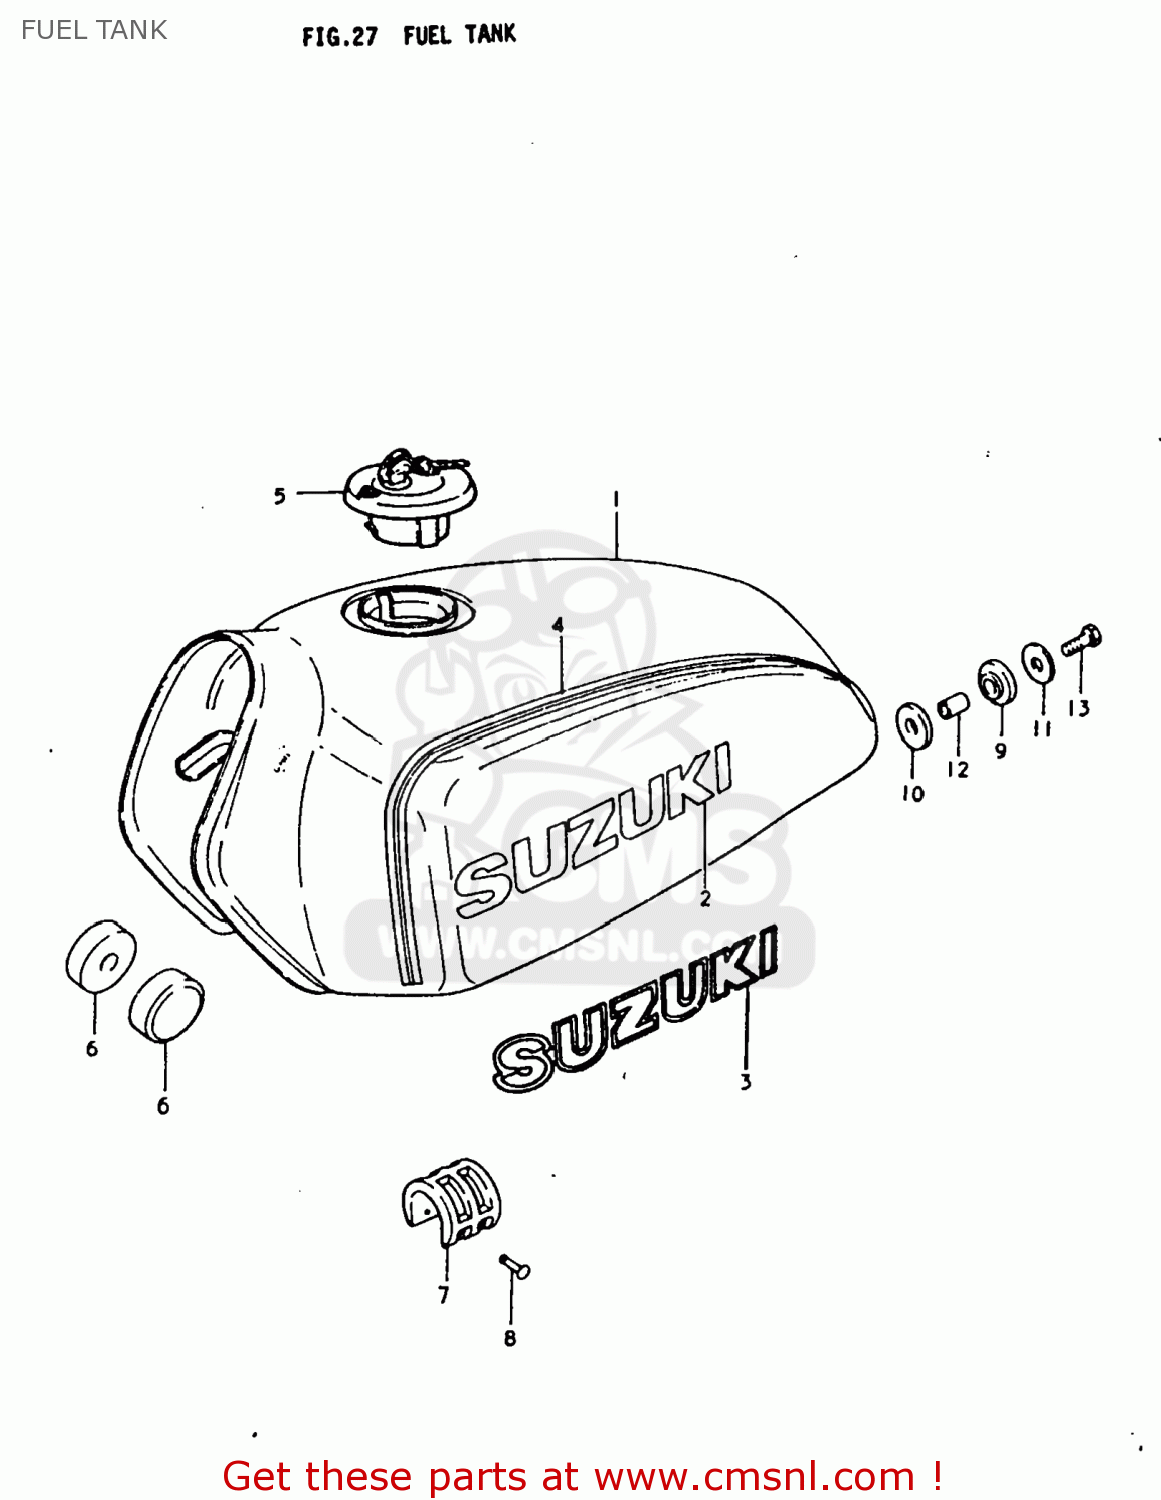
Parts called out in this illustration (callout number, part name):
1	COCK ASSEMBLY,FUEL
2	GASKET,FILTER (NAS)
3	FILTER SET,FUEL COCK
4	NET,STRAINER
5	GASKET,LEVER (NAS)
6	BOLT L:16
7	GASKET
8	HOSE
9	CLIP
